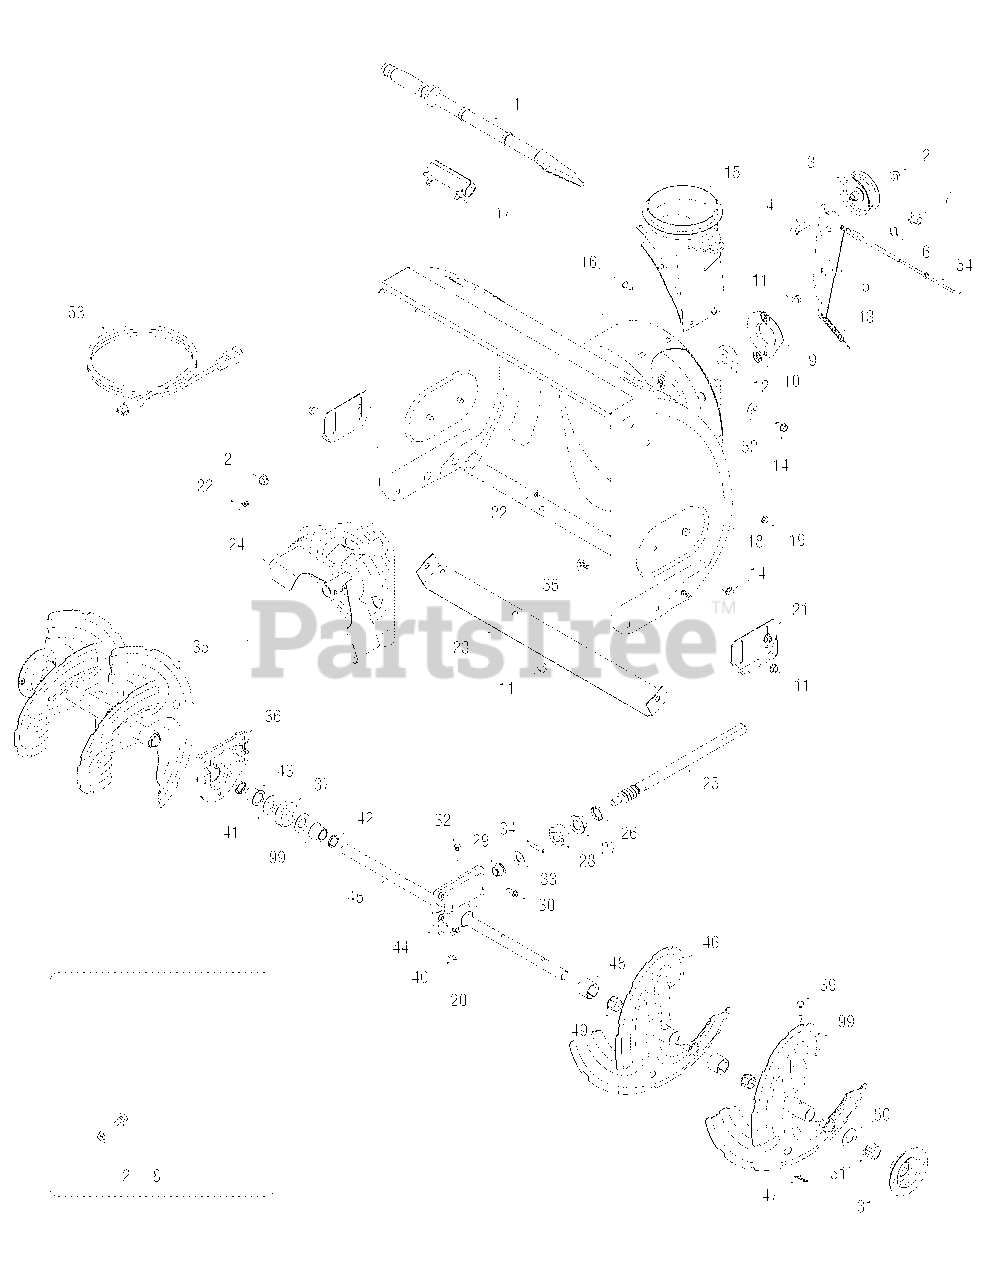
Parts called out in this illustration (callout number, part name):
1	Clean-Out Tool
2	Flange Lock Nut
3	Flat Idler Pulley
4	Hex Bolt, 3/8-16 x 1.75
6	Wave Washer
7	Shoulder Screw
8	Shoulder Screw
9	Bearing Housing
10	Push Nut
11	Flange Lock Nut, 5/16-18
12	Ball Bearing
13	Extension Spring
14	Screw, 5/16-18 x 0.750
15	Chute Adapter
16	Carriage Screw, 1/4-20 x 0.75
17	Clean-out Tool Mtg. Bracket
19	Flange Lock Nut, 1/4-20
20	Gearbox Assembly, 26-inch
22	Carriage Bolt
23	Shave Plate, Stainless, 25.66"
25	Worm Shaft
26	Oil Seal
27	Flange Bearing
28	Thrust Collar
29	Flange Bearing
30	Screw, 1/4-20 x 0.75
33	Flat Washer
34	Dowel Pin
36	Reducer Hsg.-RH
37	Worm Gear, 20T
38	Cable Tie
39	Shear Pin
40	Key
41	Flat Washer
42	Oil Seal
43	Flange Bearing
44	Reducer Hsg.- LH
45	Axle, Auger, 26"
47	Bow Tie Cotter Pin
48	Spacer
49	Flange Bushing
50	Flat Washer
51	Hex Flange Bearing
52	Bell Washer
53	Extension Cord
54	Auger Clutch Cable
